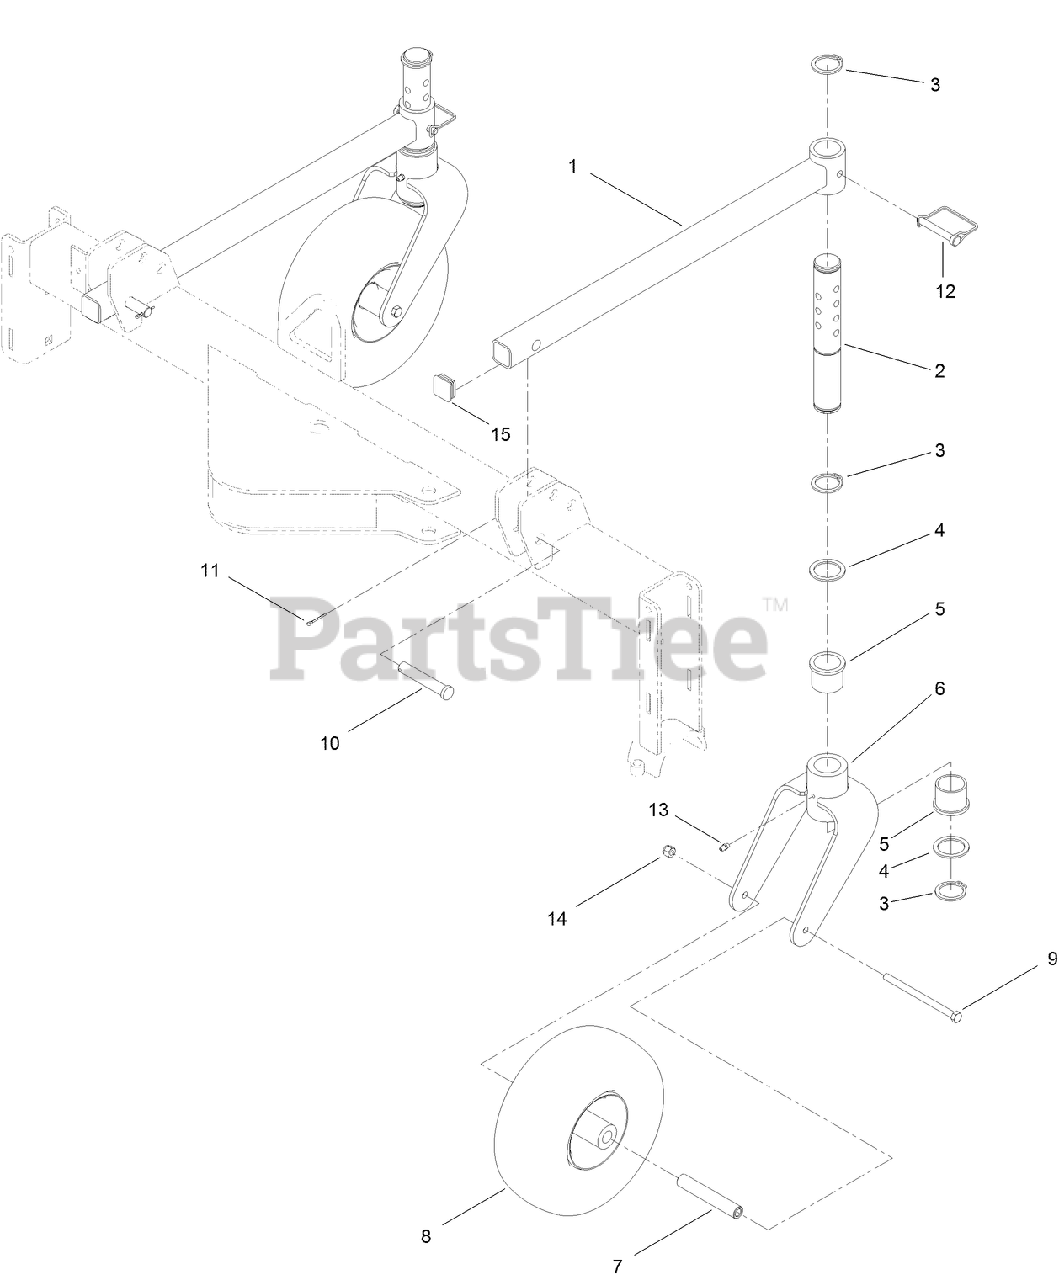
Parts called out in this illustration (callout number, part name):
1	ARM-CASTER
2	PIN-ADJUSTMENT, HEIGHT
3	RING-RETAINING
4	SPACER
5	BEARING-FLANGE
6	FORK-CASTER
7	SPACER-SLEEVE
8	WHEEL AND TIRE ASM
9	SCREW-HH
10	PIN-CLEVIS
11	PIN-COTTER
12	PIN-HITCH
13	FITTING-GREASE
14	NUT-LOCK
15	CAP-TUBE
